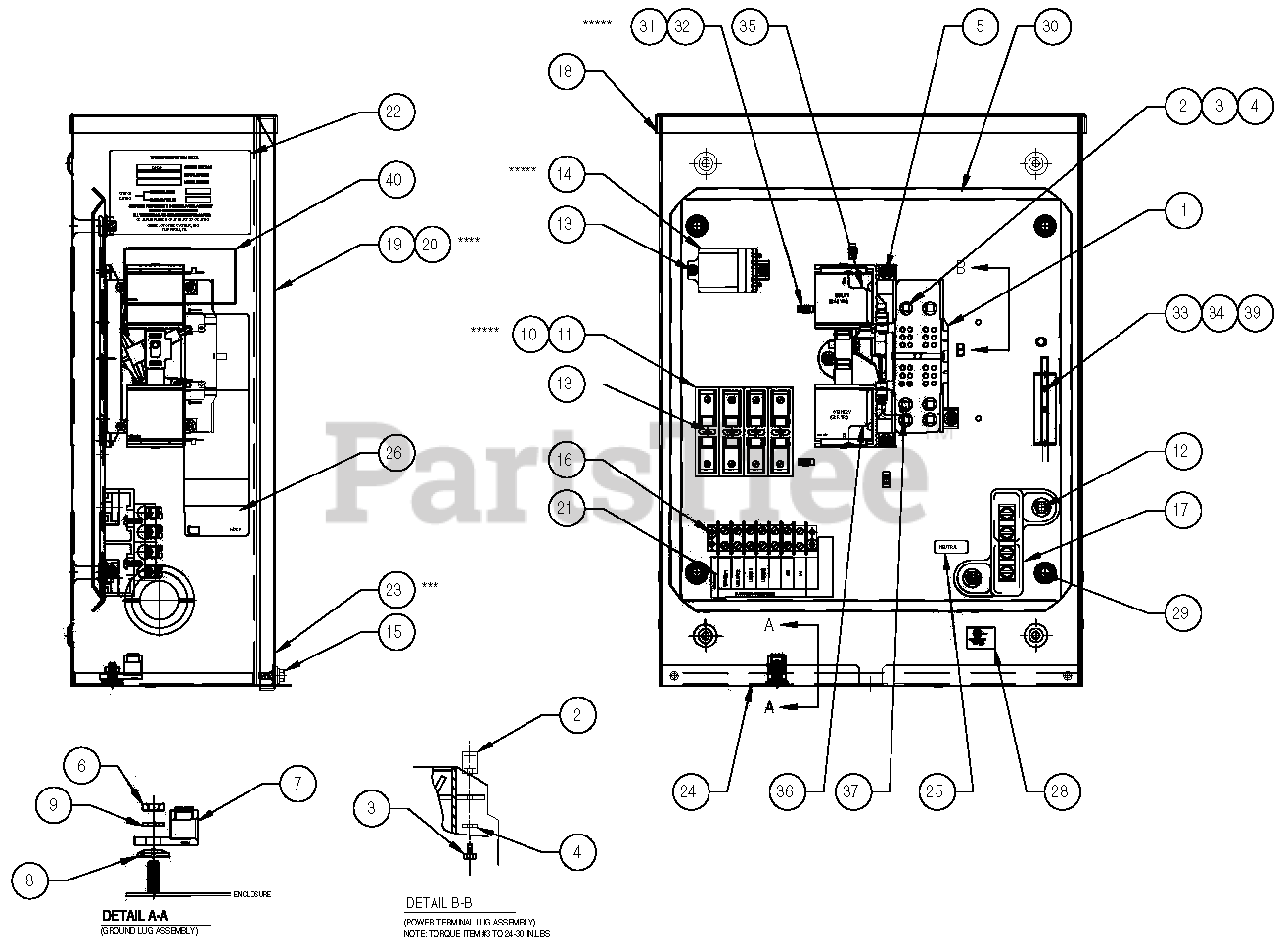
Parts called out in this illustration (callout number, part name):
1	TR SW-HSB 100A 2P 250V
2	LUG SLDLSS 1/0-#14X9/16 AL/CU
3	SCREW PPHM #10-32 X 1/4
4	WASHER LOCK #10
5	SCREW HHTT M5-0.8 X 10 BP
6	NUT HEX M8-1.25 G8 YEL CHR
7	LUG SLDLSS 2/0-#12 X 11/32 CU
8	WASHER LOCK SPECIAL 5/16
9	WASHER LOCK M8-5/16
10	FUSE 5A X BUSS
11	FUSE HOLDER
12	SCREW HHTT M6-1.0 X 12 ZINC
13	SCREW HHTT M4-0.7 X 10 BP
14	RELAY PNL 12VDC DPDT 10A@240VA
15	SCREW TH-FRM M6-1 X 16 N WA Z/JS
16	RIVET POP .156 X .675 AL
17	ASSY NEUTRAL BLOCK 100A
18	WELDMENT XFER SW BOX HSB
19	COVER TRANSFER SWITCH BOX HSB
21	DECAL TERMINAL STRIP
22	DECAL SWITCH RATING
23	DECAL-LIVE CIRCUIT
24	DECAL GROUND LUG
25	DECAL NEUTRAL
26	DECAL MANUAL 5A FUSE
27	DECAL TEST SEQUENCE 3R
28	DECAL-UL LIST HSB
29	NUT HEX FL WHIZ 3/8-16
30	SUBPLT TRANSFER SWITCH HSB
31	HOLDER CABLE TIE
32	TIE WRAP UL 3.9" X .10" NATL
33	BRACKET, ARM EXTENDER
34	ARM EXTENDER PIN
37	WIRE E1
39	SCREW HWHS #6-25 X 3/8 ZNC
40	DECAL TRANSFER SWITCH DATA 100
